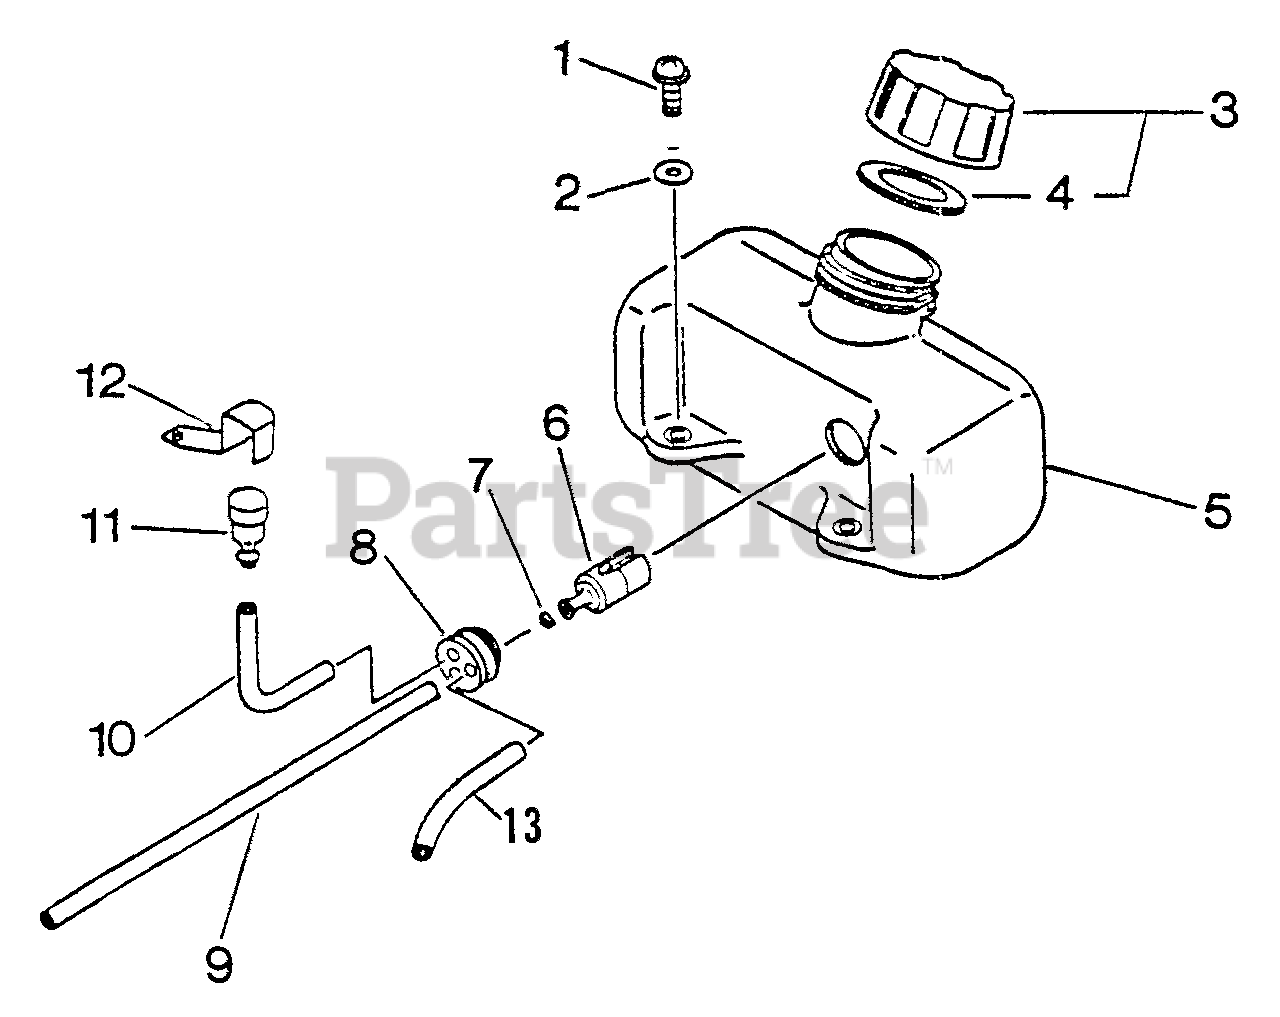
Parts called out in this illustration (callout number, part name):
1	SCREW - 5X16
2	WASHER - 5
3	CAP ASSY
4	GASKET, CAP
5	TANK, FUEL
6	FILTER, FUEL
7	CLIP - 6
8	GROMMET
9	PIPE - 3X5X180 -- BLACK
10	PIPE - 3X6X70 -- CLEAR
11	VENT, FUEL TANK
13	PIPE - 3X6X110 -- CLEAR
